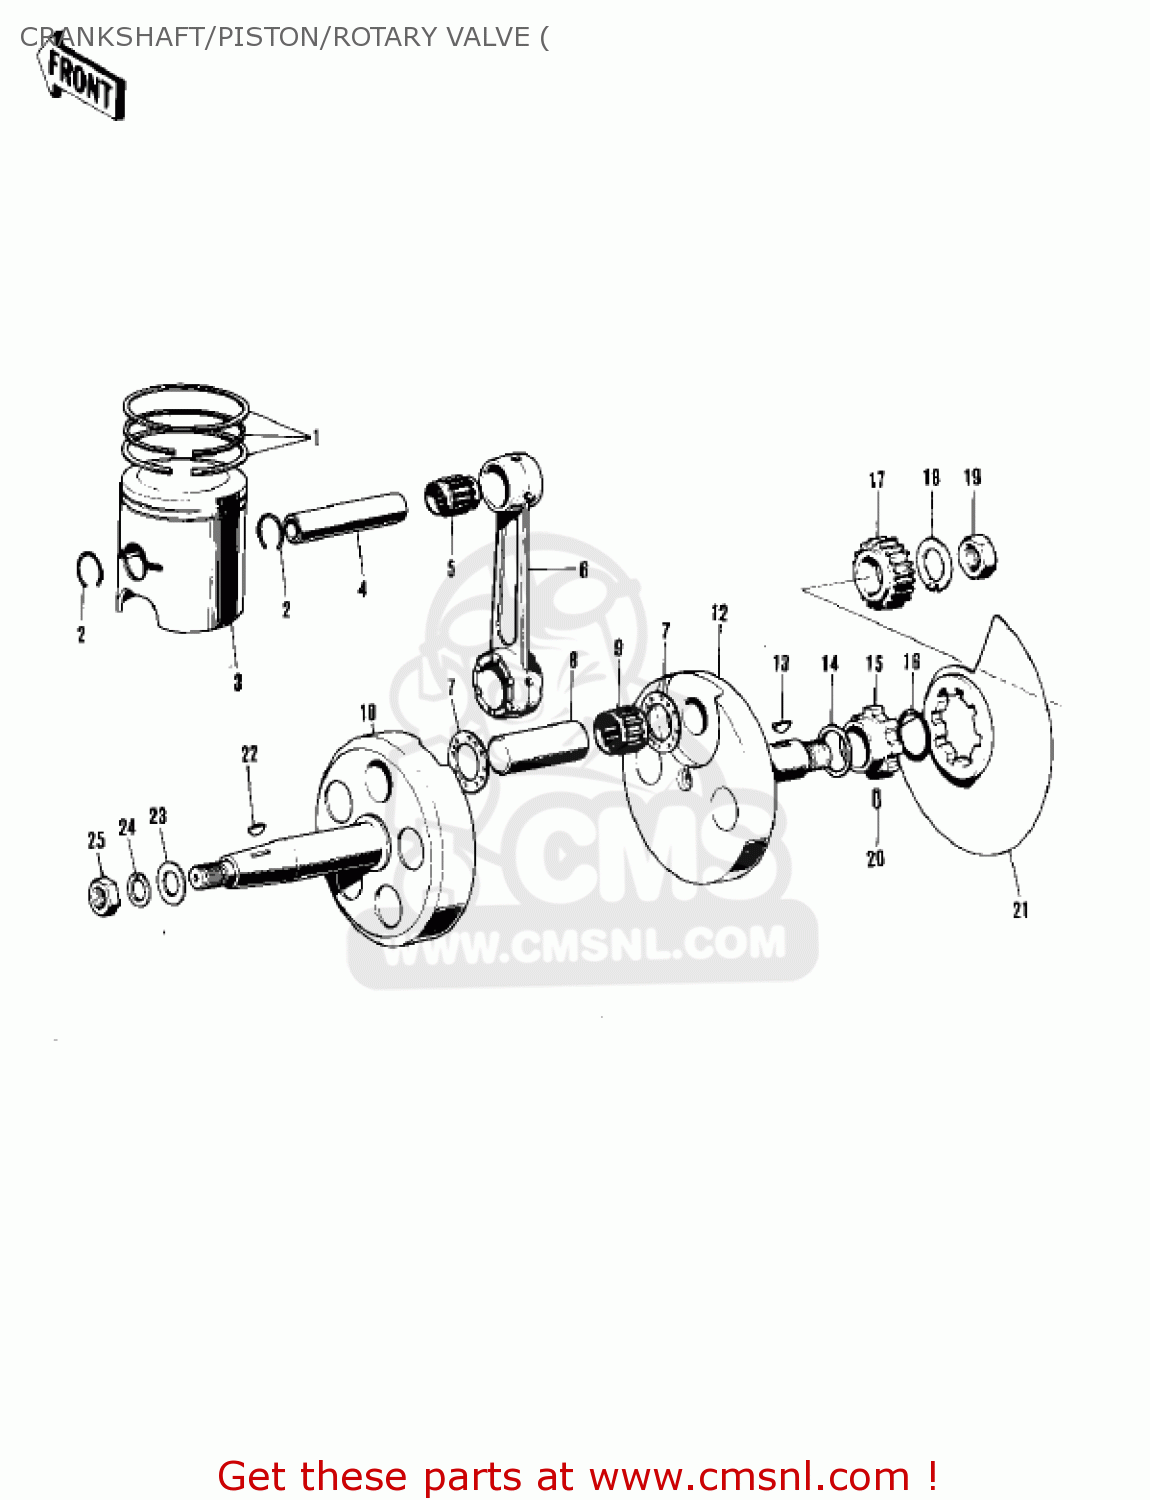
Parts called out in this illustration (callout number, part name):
1	RING-SET-PISTON,STD
2	CIRCLIP-PISTON PIN
3	PISTON,STD
4	PIN-PISTON
5	BEARING-NEEDLE,R1422P
7	SPACER,22.5X37X1.0
8	CRANK PIN
9	BEARING-NEEDLE,22VS29
10	CRANKSHAFT,L.H
12	CRANKSHAFT,R.H
13	WOODRUFF KEY-PRY PINI
14	COLLAR-CRANKSHAFT
15	COLLAR-R.H CRNK SHFT
16	RING-O,22MM
17	PINION,PRIMARY
18	WASHER,LOCK
19	NUT,18MM
20	ROLLER,4X12
21	VALVE-ROTARY DISC
22	WOODRUFF KEY
23	WASHER,14.5X25X3.6
24	WASHER-SPRING,14MM
25	NUT,14MM
?	CONNECTING ROD SET
